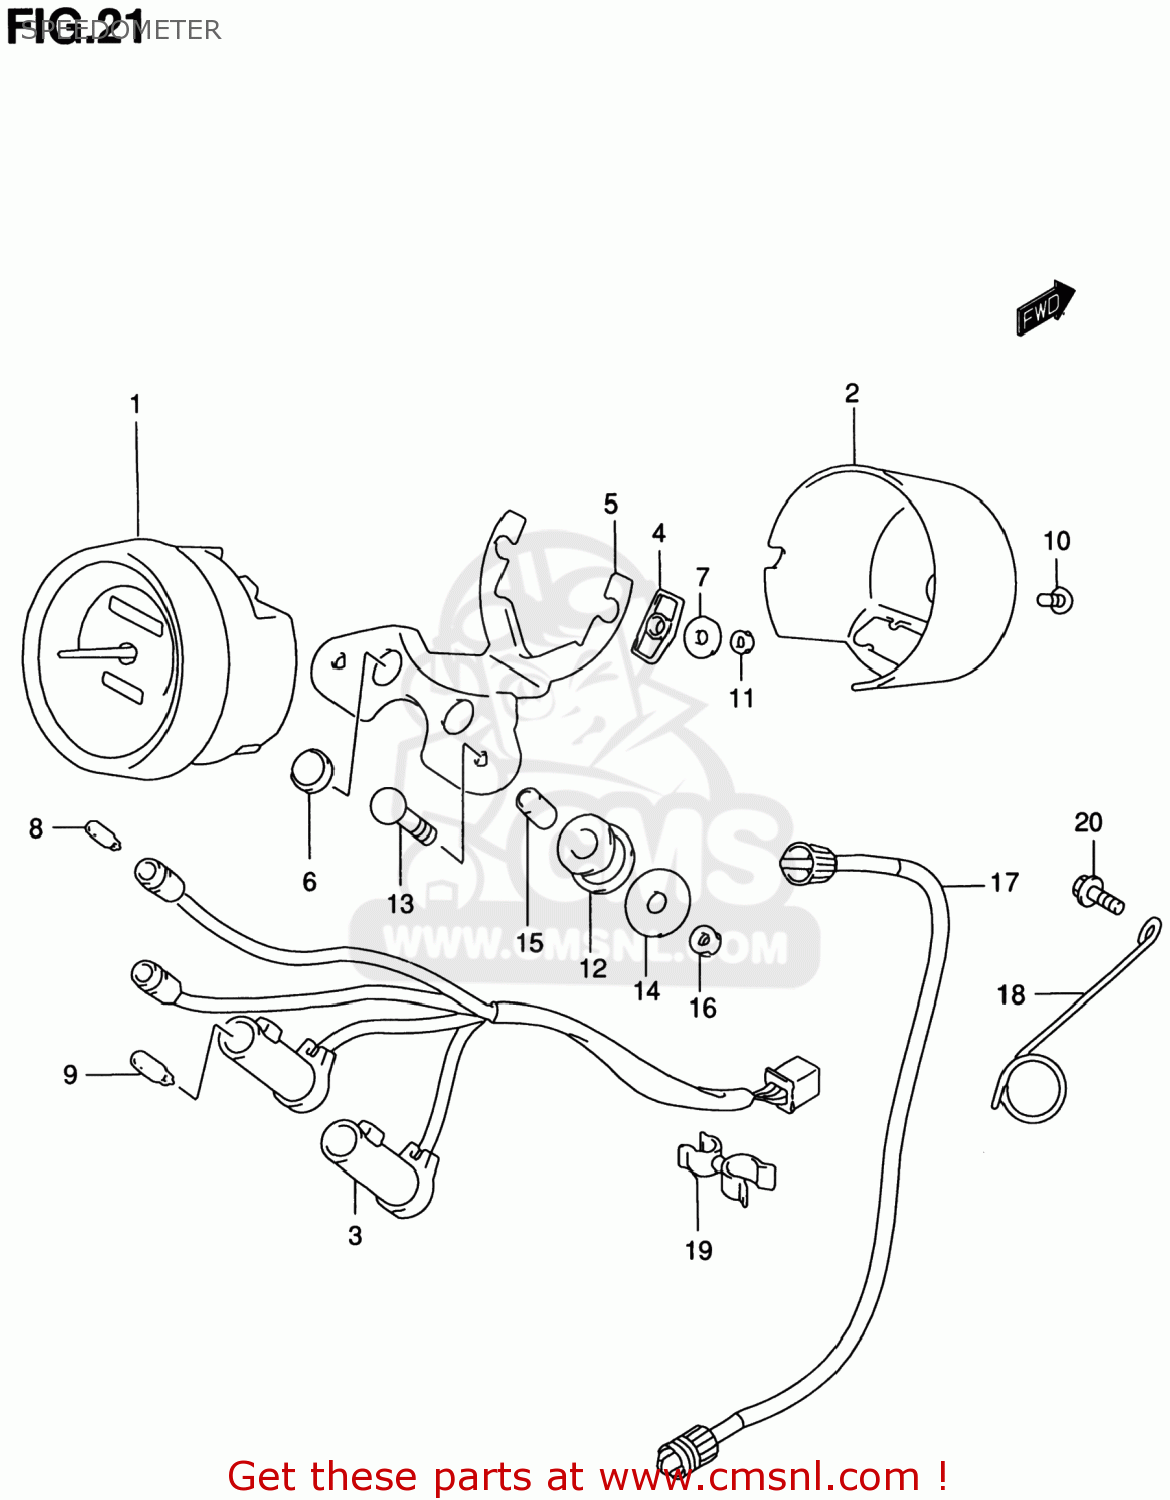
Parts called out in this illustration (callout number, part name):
1	SPEEDOMETER
2	COVER,UNDER(CHROMUN)
3	SOCKET ASSY
4	CUSHION,DAMPER
5	BRACKET,METER
6	LENS(GREEN)
7	WASHER(5.2X16X1)
8	BULB(12V3.4W,T10)
9	BULB(12V1.7W,T6.5)
10	SCREW
11	NUT
12	CUSHION,METER BRACKET
13	BOLT(6X30)
14	WASHER(6.5X28X1.6)
15	SPACER(6.5X10X15.7)
16	NUT 6MM
17	CABLE ASSY,SPEEDOMETER
18	GUIDE,SPEEDOMETER CABLE
19	CLIP
20	BOLT
